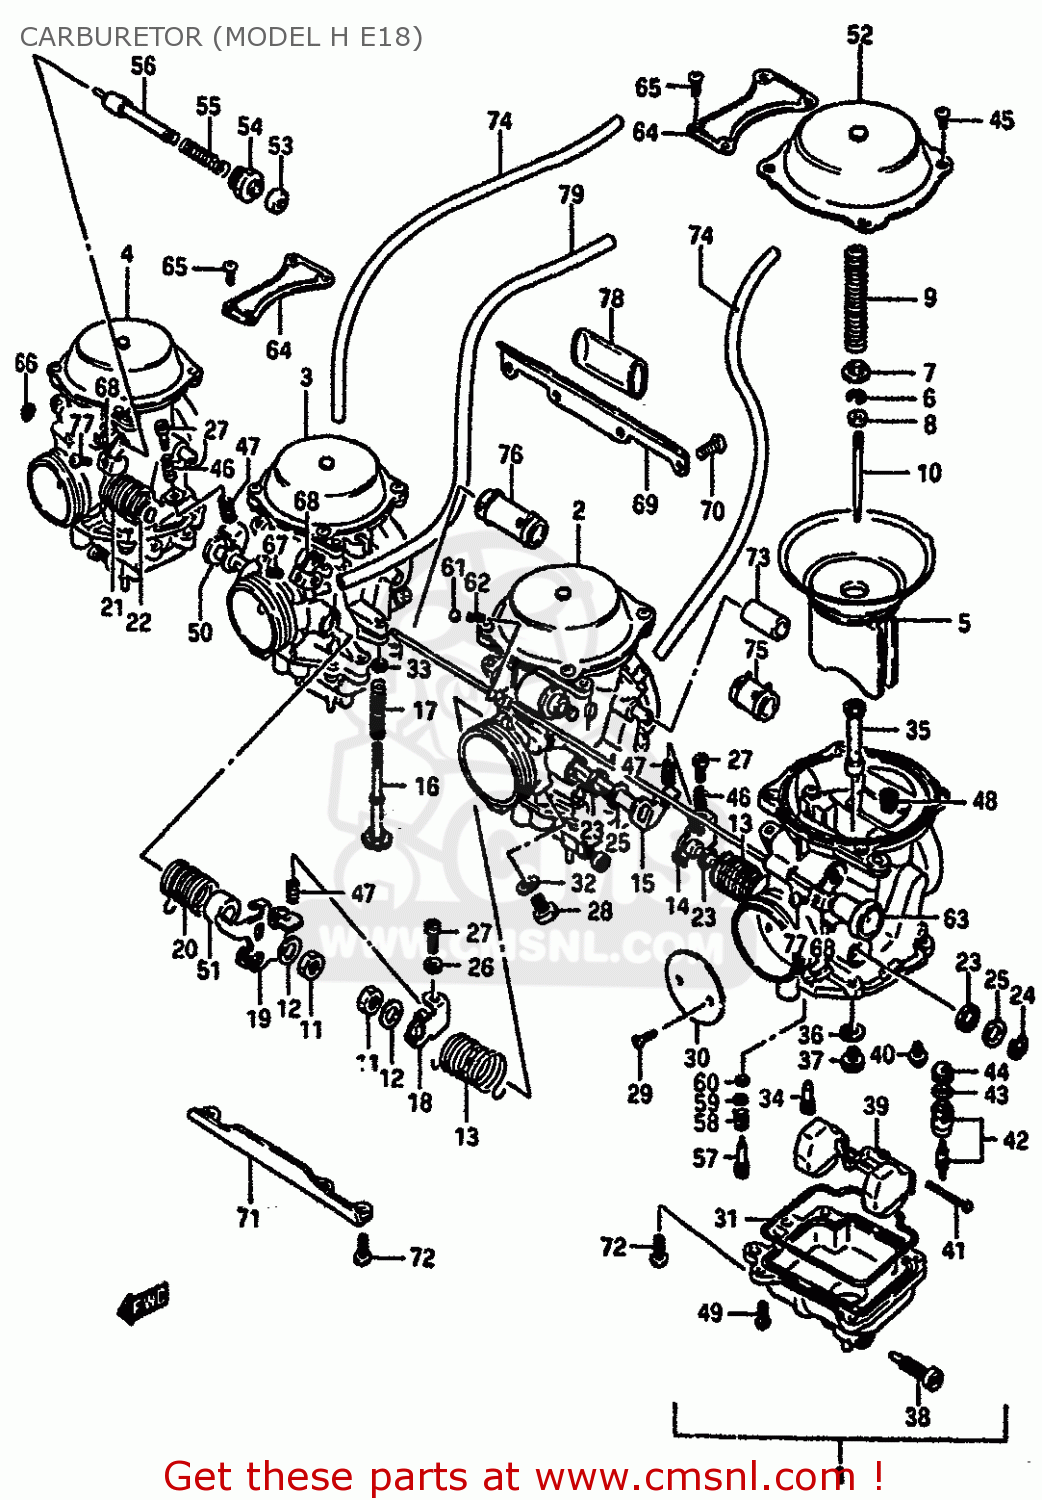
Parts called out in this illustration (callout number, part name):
1	CARBURETOR ASSY,LH
2	CARBURETOR ASSY,ML
3	CARBURETOR ASSY,MR
4	CARBURETOR ASSY,RH
5	DIAPHRAGM
6	CLIP
7	RING
8	RING
9	SPRING
10	NEEDLE,JET (AC8-3)
11	NUT
12	WASHER
13	SPRING
14	SHAFT ASSY
15	SHAFT ASSEMBLY
16	SCREW
17	SPRING
18	LEVER
19	LEVER ASSEMBLY
20	SPRING
21	SPRING
22	SHAFT ASSEMBLY
23	SEAL
24	E RING
25	GASKET,THROTTLE SHAFT (NAS)
26	NUT,THROTTLE ROD
27	SCREW
28	SCREW
29	SCREW
30	VALVE,THROTTLE (130)
31	O RING,FLOAT CHAMBER
32	WASHER
33	WASHER
34	JET ,PILOT (35)
35	JET NEEDLE (Q-0)
36	WASHER,NEEDLE NOZZLE
37	JET,MAIN(117.5)
38	SCREW,DRAIN
39	FLOAT
40	SCREW
41	PIN,FLOAT
42	VALVE ASSY,NEEDLE
43	O-RING,NEEDLE VALVE
44	FILTER
45	SCREW
46	SPRING
47	SPRING,THROTTLE SCREW
48	JET
49	SCREW
50	SHAFT ASSEMBLY
51	RING
52	COVER,DIAPHRAGM
53	CAP,STARTER VALVE
54	GUIDE SCREW,PLUNGER
55	SPRING
56	PLUNGER ASSY
57	SCREW,PILOT
58	SPRING
59	GASKET
60	O RING,PILOT AIR SCREW
61	BALL,CARBURETOR
62	SPRING
63	SHAFT ASSEMBLY
64	PLATE
65	SCREW
66	E-RING
67	SCREW
68	LEVER
69	PLATE
70	SCREW
71	PLATE
72	SCREW
73	HOSE,CARBURETOR
74	HOSE
75	HOSE SET (3X5X18)
76	HOSE ASSY
77	SCREW
78	HOSE
79	HOSE
